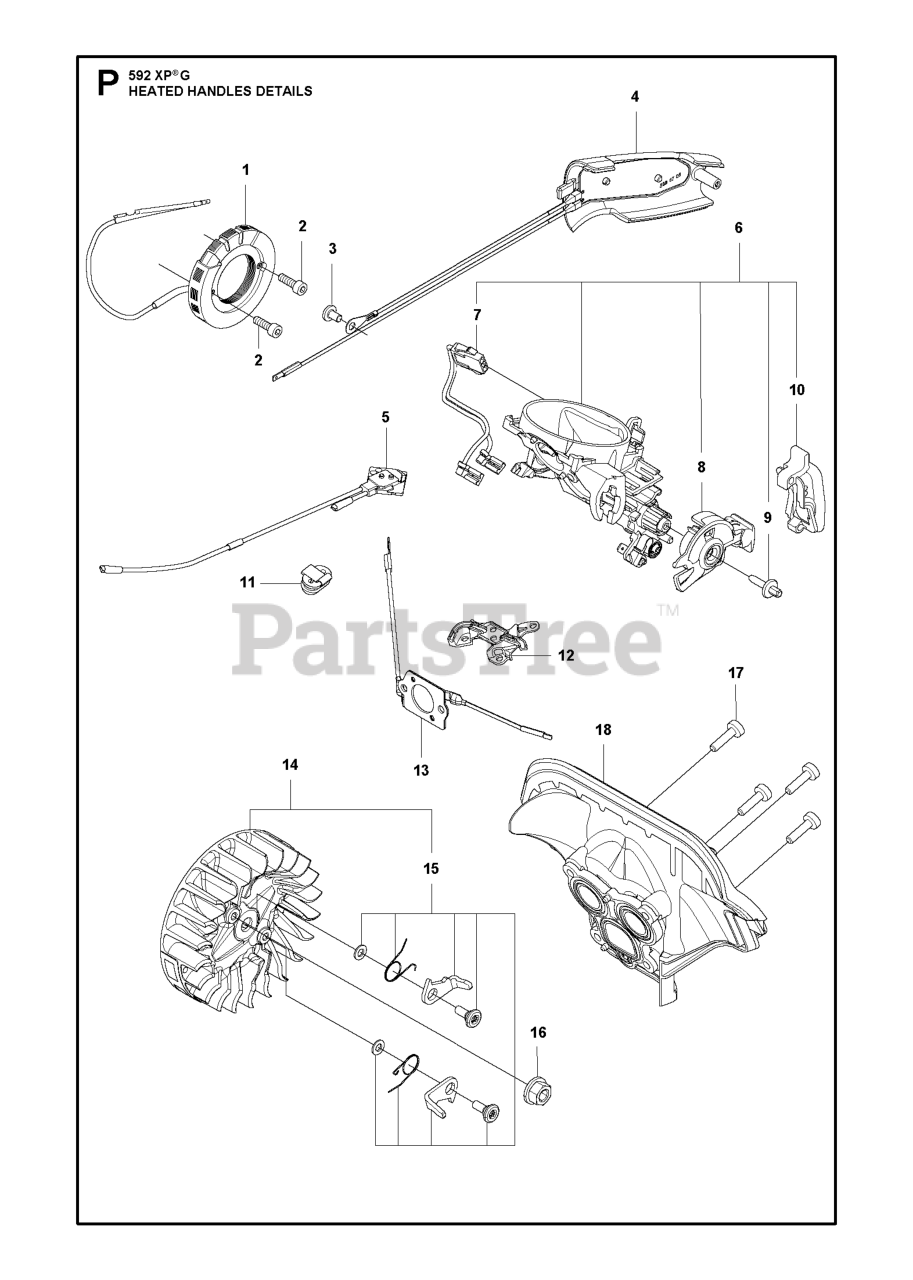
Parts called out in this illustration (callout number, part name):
1	STATOR ASSY
2	SCREW ITXSCM M4X15 T27 12.9 T
4	HANDLE INSERT ASSY XPG
5	THERMOSTAT ASSY
6	INLET ELBOW ASSY XPG
7	WIRING ASSY STOP
8	CHOKE CONTROL ASSY
10	SEALING CHOKE CONTROL
12	RETAINER THERMOSTAT
13	FOIL ELEMENT CARBURETTOR
14	FLYWHEEL ASSY D114 G
15	SCREW KIT PAWL 90CC SPARE PART
16	NUT W/ WASHER
17	SCREW ITXSCM M4X15 T27 12.9 T
18	INLET PIPE ASSY WINTER
